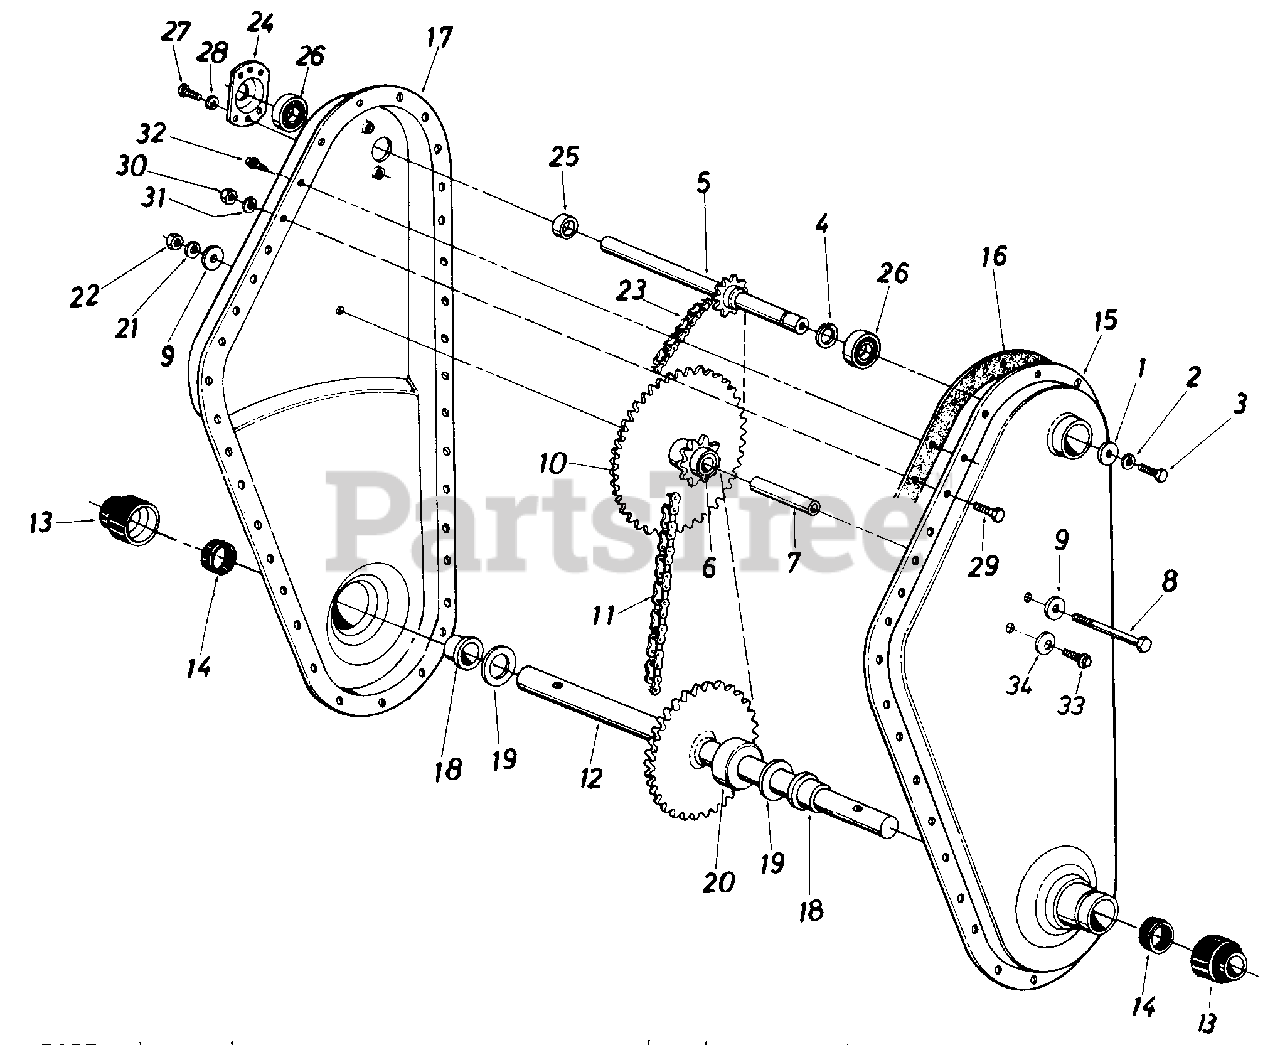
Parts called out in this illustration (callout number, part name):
1	Fl-Wash. 1/4" I.D. x .93" O.D. x .1 20
2	L-Wash. 1/4" I.D.
3	Hex Bolt 1/4-28 x .62" Lg. w/ Patch
4	External Snap Ring-5/8" Dia.
5	Input Shaft Ass'y.
6	Bearing 5/8" I.D. x 3/4" O.D. x 1.860" Lg.
7	Sprocket Hub Tubing 3/8" I.D. x 5/8" O.D. x 1.90
8	Hex Bolt 3/8-24 x 2.75" Lg.
9	Fl-Wash 3/8" I.D. x 1.25 O.D. x .10
10	Sprocket Ass'y.
11	#50 Chain 5/8" Pitch x 46 Links Endless
12	Tine Shaft Ass'y.
13	Dust Cup
14	Seal Ring Single Lip, Springless
19	Fl-Thrust Wash. 1.0" I.D. x .03 Thk.
20	Step Spacer
21	L-Wash. 3/8" I.D.
22	Hex Nut 3/8-24 Thd.
23	#35 Chain 3/8" Pitch x 52 Links Endless
24	Bearing Housing 1.38" I.D.
25	Spacer
26	Ball Bearing .625" I.D. x 1.38" O.D. x .437
27	Hex Wash. SF-Tap Scr. 1/4-20 x .50" Lg.
28	L-Wash. 1/4" I.D.
29	Hex Bolt 5/16-18 x .75" Lg.
30	Hex Nut 5/16-18 Thd.
31	L-Wash. 5/16" I.D.
32	Hex Wash. SF-Tap Scr. 1/4-20 x.50" Lg.
33	Hex Wash. Hd. Tap Scr. 1/4-20 x.38" Lg.
34	Bell-Wash. .265" I.D. x .75" O.D.
